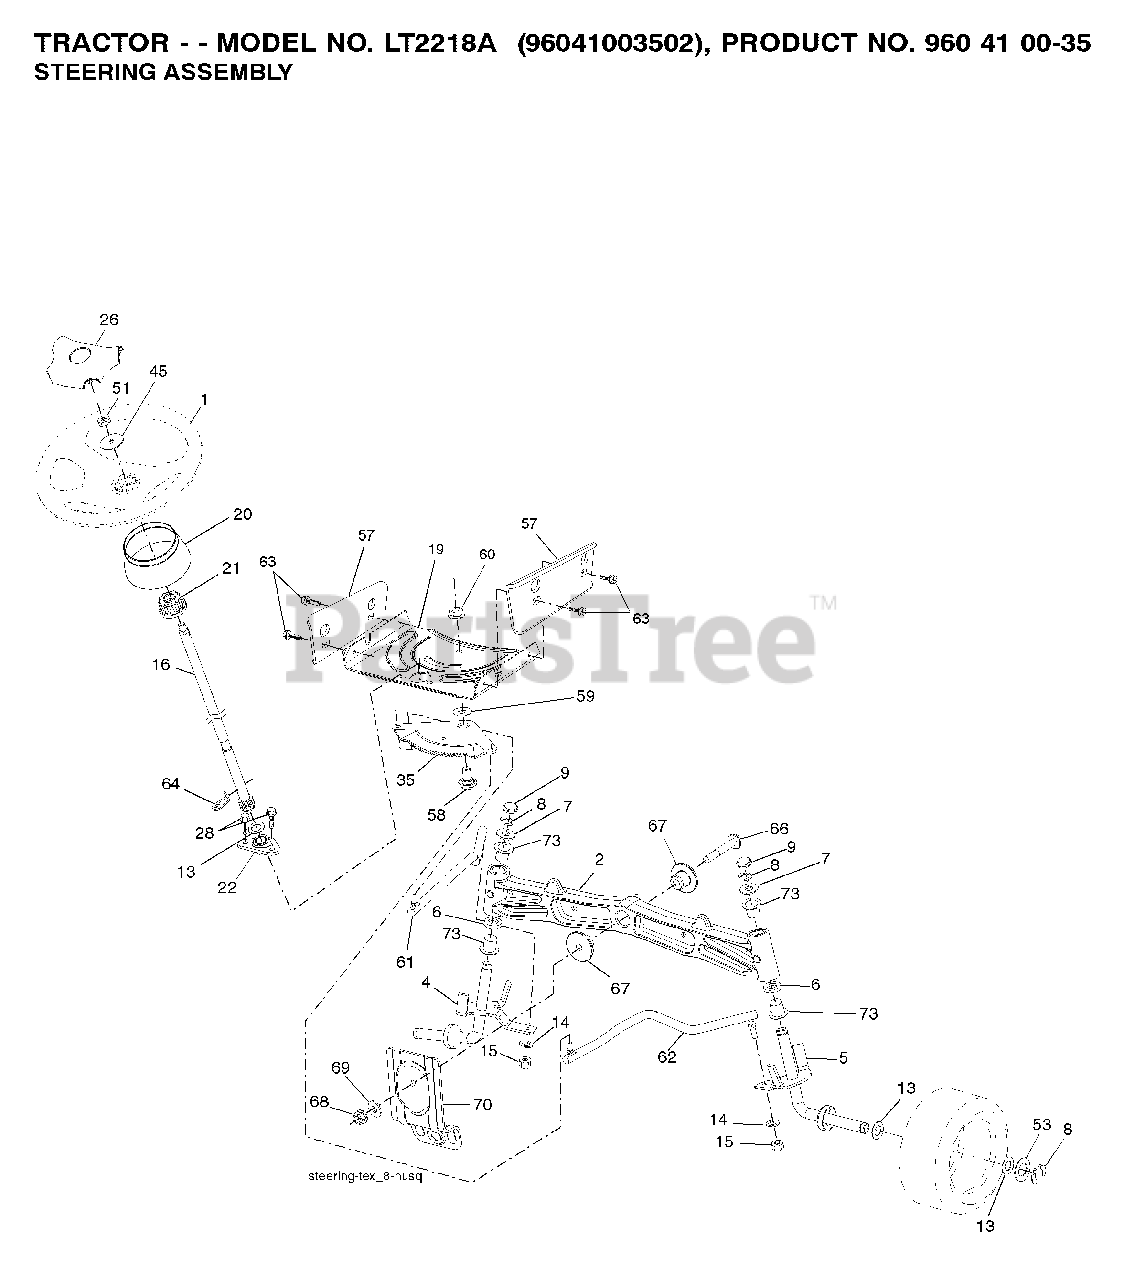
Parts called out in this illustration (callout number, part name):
1	WHEEL.STEERING.PREM.2.BLK
2	AXLE.HALF.ASM.WELDED
4	SPINDLE.WELDED.LH.15"TEX
5	SPINDLE.WELDED.RH.15"T
8	RING CLIP
9	CAP.SPINDLE
14	WASHER, LOCK 3/8
15	NUT CROWNLOCK 3/8-24
16	SHAFT.STEER.STEALTH.DD
19	PLATE.STEER.DDL.NLT/NG
20	BOOT.STEERING.
21	ADAPTER, WHEEL STNG..
22	BUSHING.ASM.STEERING.A
26	INSERT.CAP.STRG.WH.BLACK
28	SCREW, 3/8-16X3/4
35	GEAR.SECTOR.PLATE.DDL.
45	WASHER.11/32
51	NUT.HEX.1/2-20
53	WASHER.HARDENED
57	BRACKET.UPSTOP.TEX
58	BOLT.SHOULDER.SECTOR.P
59	WASHER.THURST.SECTOR.S
60	NUT FLANGE LOCK 5/8-11
61	DRAGLINK.LH.BALLSTUD.D
62	DRAGLINK.RH.BALLSTUD.D
63	SCREW
64	RETAINER.CLIP.SPRING.S
66	BOLT HEX FGHD 7/16-14 X 3 SERR
67	BUSHING.PM.FRONT AXLE
68	NUT.LOCK.FLANGE.7/16
69	WASHER.1.5X.505X.118
70	BRKT.DECK.SUSPENSION.F
74	BRNG T
